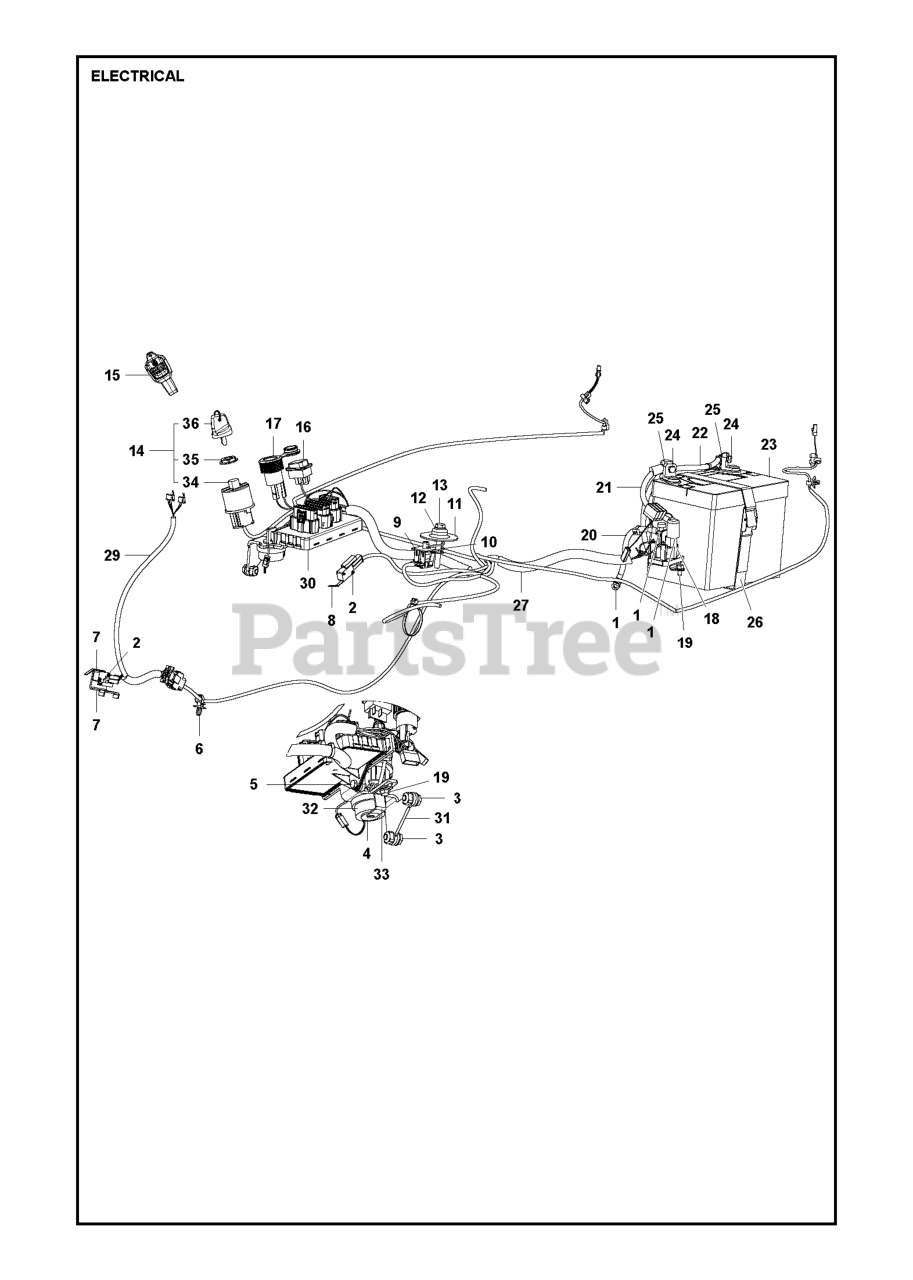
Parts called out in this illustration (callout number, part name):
5	SCREW
8	MICRO SWITCH
9	SWITCH SEAT, 4 PIN NC/NO
12	WASHER BRB 8.4X17
14	IGNITION SWITCH
24	SCREW EHHM
34	IGNITION SWITCH
36	IGNITION KEY
